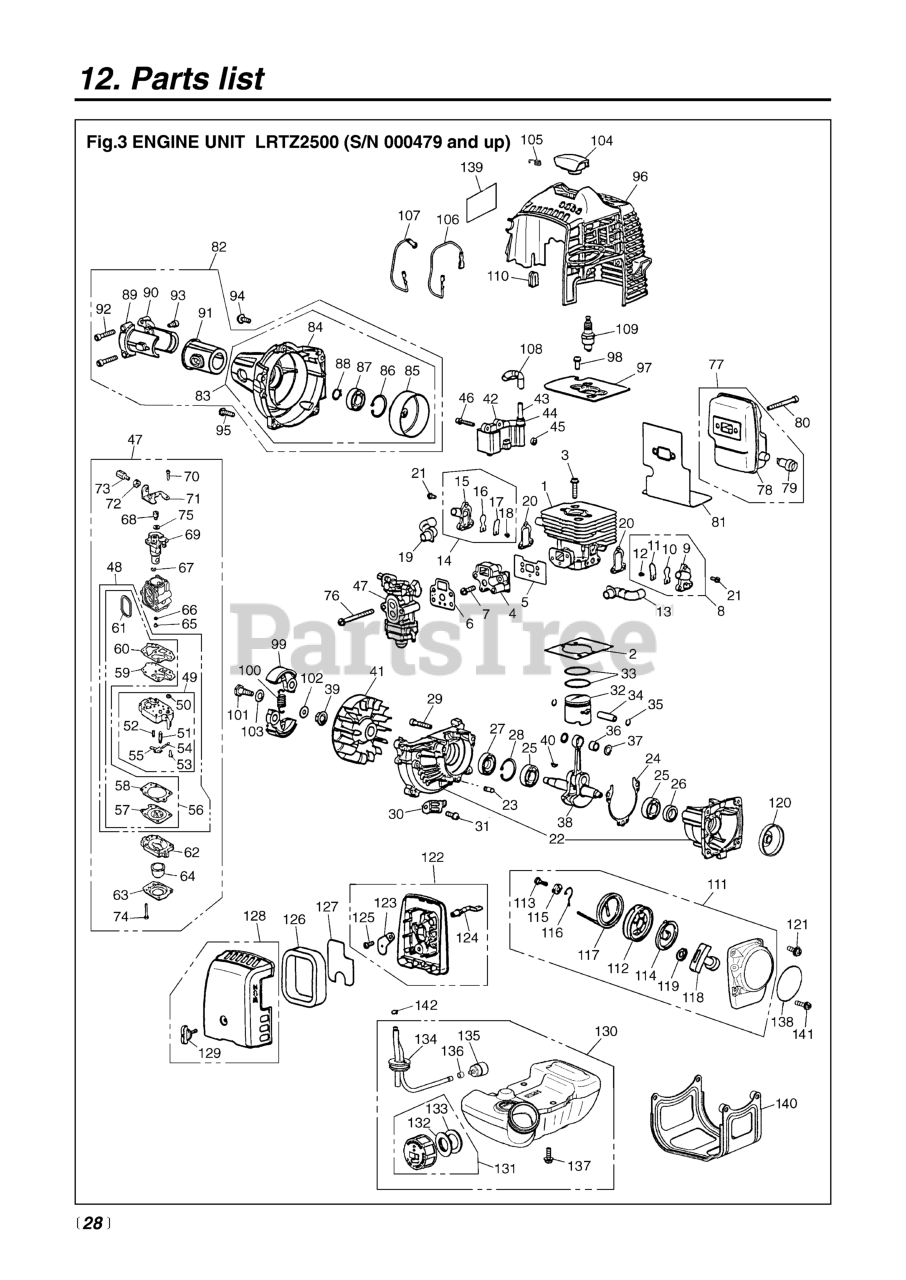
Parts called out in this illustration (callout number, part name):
1	CYLINDER (RPLS -12110)
2	GASKET, BASE
3	BOLT, M5 X 22
4	INSULATOR (RPLS. -13160/13161)
5	GASKET, INSULATOR
6	GASKET, CARBURETOR
7	SCREW, M5X20 (RPLS.1400-75510)
8	REED VALVE (RPLS 4810-16100)
9	VALVECASE
10	VALVE, REED
11	STOPPER
12	SCREW, M3 x 8
13	PIPE, AIR
15	VALVE CASE (F) (RP.4810-16210)
16	VALVE, REED
17	STOPPER
18	SCREW, M3 x 8
19	PIPE, AIR (F)
20	GASKET, VALVE
21	SCREW
22	CRANKCASE-C
23	PIN
24	GASKET
25	BEARING
26	SEAL
27	SEAL, OIL (RPLS 1140-21220)
28	RING, SNAP, M28 x 1.2
29	BOLT, M5 X 30
31	SCREW, M5 X 10
32	PISTON
33	RING, PISTON
35	RING, SNAP (RPLS 1101-41320)
37	WASHER
38	CRANKSHAFT COMPLETE
40	KEY
41	ROTOR
42	COIL-A
43	CORD
44	CAP
45	SPACER (RPLS -71260)
46	BOLT, M4 x 22
47	CARBURETOR (WYA-1-1)
48	REBUILD KIT
49	BODY-A
50	SCREEN
51	VALVE, INLET
53	SCREW
54	PIN
55	LEVER
56	KIT, GASKET (REPLACES-06020)
57	DIAPHRAGM
58	GASKET, DIAPHRAGM
59	DIAPHRAGM, PUMP
60	GASKET, PUMP
61	RING
62	BODY, PURGE
63	COVER, PUMP
64	PUMP, PRIMING
65	JET (USE -81251)
66	RING, O
67	RING
68	SWIVEL
69	VALVE ASSY
70	SCREW
72	NUT, CABLE ADJUSTER
73	SCREW, CABLE ADJUSTER
74	SCREW
75	WASHER
76	SCREW, M5 x 60
77	MUFFLER ASSEMBLY
78	MUFFLER (REPLACES -15110)
79	ARRESTER
80	BOLT, M5 x 50
81	GASKET (RPLS T1501-15210)
82	COVER ASSY. (REPLACES -31001)
83	COVER COMP. (REPLACES -31101)
84	COVER, FAN (REPLACES -31110)
85	DRUM (REPLACES 4810-31122)
86	RING, SNAP, M28 x 1.2
87	BEARING
88	RING, SNAP (RPLS 3130-13270)
89	BRACKET (A) (RPLS -31210)
90	BRACKET (B) (REPLACES -31220)
91	CUSHION
92	BOLT, M5 X 30
93	BOLT (USE 3310-31720)
94	SCREW
95	SCREW, M5X20 (RPLS.1400-75510)
96	COVER, ENGINE (RPLS -32110)
97	PLATE, CYLINDER
98	SCREW, M5 X 10
99	SHOE
100	SPRING
101	BOLT
102	WASHER, FLAT (USE 182303)
103	WASHER (RPLS -51241)
104	CAP (RPLS 4810-72110)
105	SPRING
106	CORD (BLACK)
107	CORD, EARTH (RED)
108	TUBE
110	GROMMET
111	RECOIL ASSEMBLY
112	REEL
113	SCREW
114	SPRING, SPIRAL
115	COLLAR
116	ARM
117	ROPE (REPLACES 4500-75160)
118	KNOB (RPLS -75420)
119	PLATE, STOPPER
120	PULLEY
121	SCREW
122	BODY ASSEMBLY
123	PLATE, CHOKE
124	LEVER, CHOKE
125	SCREW (REPLACES 50030272)
126	ELEMENT
127	SCREEN
128	COVER ASSEMBLY
129	KNOB (RPLS -82220)
130	TANK ASSY (RPLS-85001)
131	CAP ASSY (RPLS -85201)
132	HOLDER (REPLACES -85230)
133	PACKING
134	PIPE COMPLETE
135	FILTER ASSY
137	SCREW
138	LABEL, RECOIL
139	LABEL, COVER
140	GUARD (RPLS 4810-31911)
141	SCREW, M5 x 25
142	CLIP
